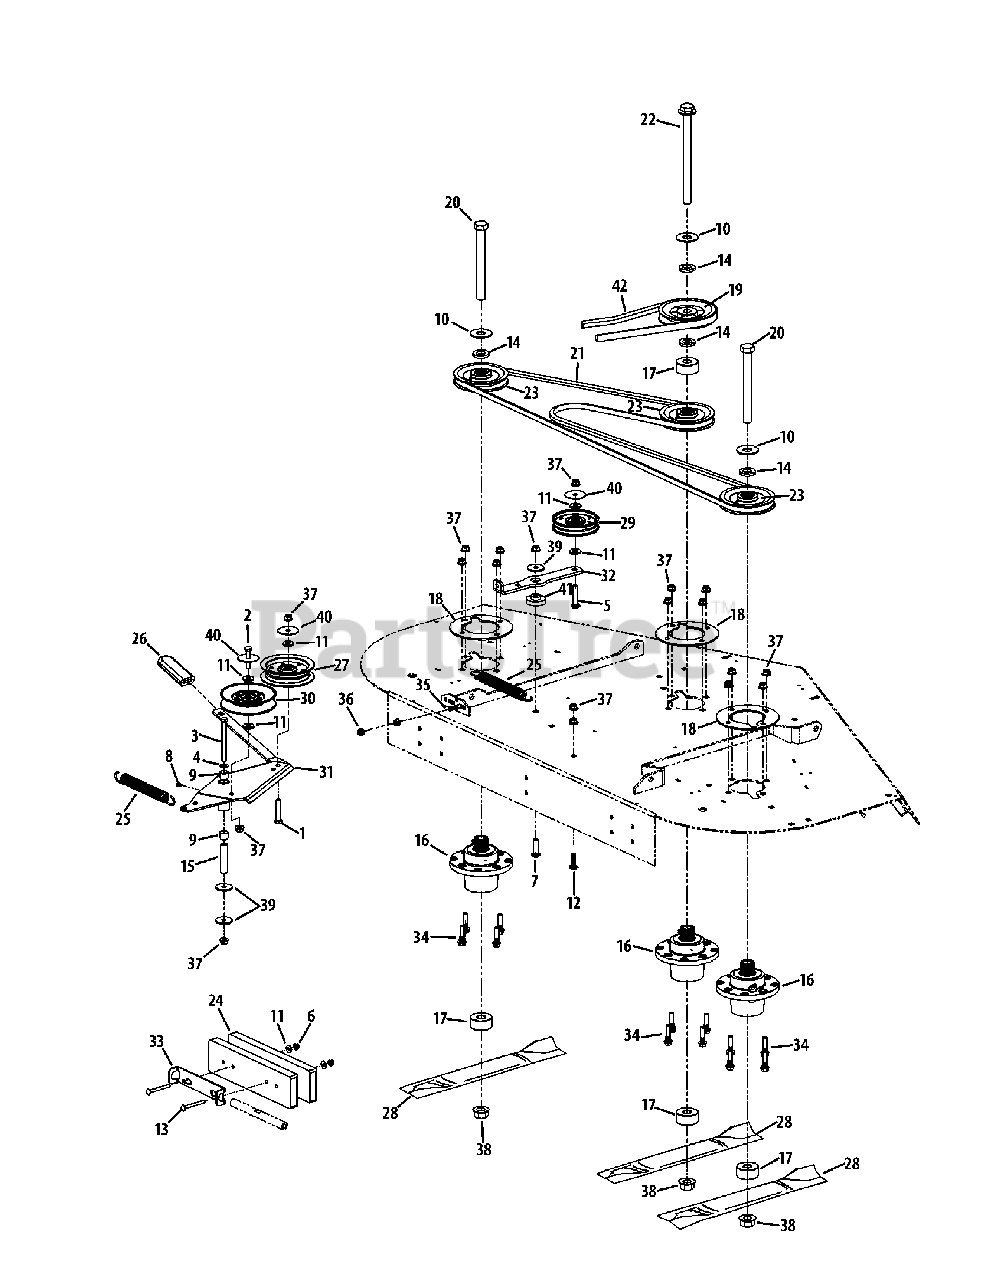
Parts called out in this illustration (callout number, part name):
1	Hex Screw, 3/8-16 x 2.00
2	Hex Screw, 3/8-16 x 1.75
3	Hex Screw, 3/8-16 x 4.00
4	Washer, .406 x .813 x .063
5	Carriage Bolt, 3/8-16 x 2.00
6	Flange Counter Lock Nut, 3/8-16
7	Carriage Bolt, 3/8-16 x 1.50
8	Grease Fitting, 1/4-28
9	Sleeve Bearing, .628 x .753 x .625
10	Washer, .781 x 2.00 x .105
11	Washer, .406 x 1.00 x .105
12	Carriage Bolt, 3/8-16 x 1.25
13	Carriage Bolt, 3/8-16 x 3.50
14	Spacer, .812 x 1.47 x .218
15	Spacer, .390 x .635 x 2.75
16	Spindle Assembly
17	Spacer, .760 x 2.00 x .925
18	Support Plate
20	Hex Screw, 3/4-16 x 7.00
21	V-Belt
22	Hex Screw, 3/4-16 x 9.00
25	Extension Spring, .94 x 7.57 x .14
26	Flat Grip, 1.0 x 3.2 x .25
27	Idler Pulley
28	Hi-Lift Blade, 21.0
28	Bahia Blade (Low Lift)
29	Idler Pulley
30	Idler Pulley
31	Double Idler Handle
32	Deck Idler Arm
35	Hex Flange Bolt, 3/8-16 x 1.5
36	Flange Lock Nut, 5/16-18
37	Flange Lock Nut, 3/8-16
38	Flange Lock Nut, 3/4-16
39	Flat Washer, .390 x 1.500 x .134
40	Flat Washer, .406 x 1.92 x .060
41	Shoulder Spacer, .854 x .280
